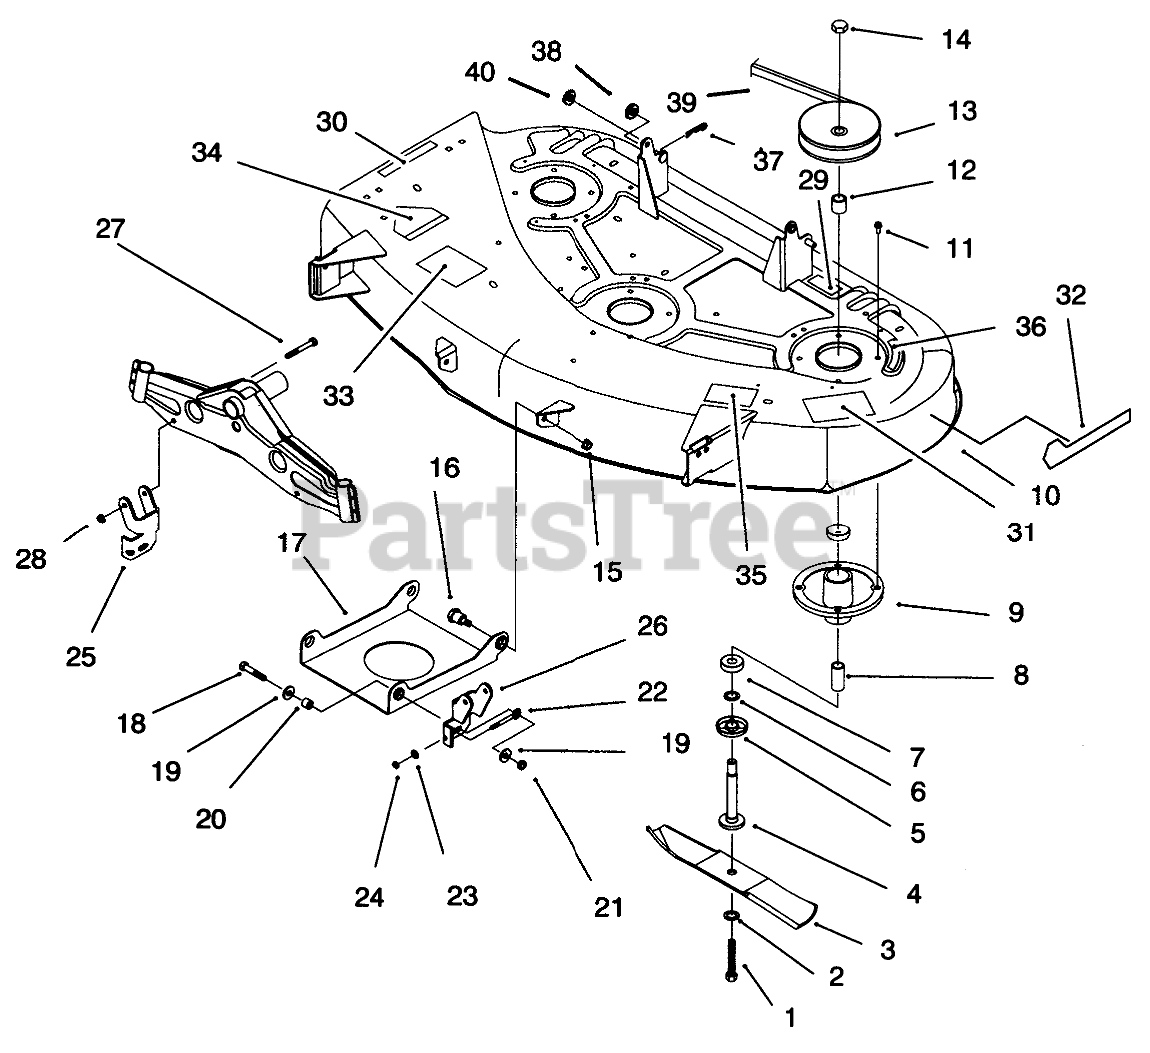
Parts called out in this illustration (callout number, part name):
1	SCREW-HH
2	WASHER-BELLEVILLE
3	Blade-Recycler
4	SHAFT-SPINDLE
5	SHIELD-BEARING
6	SPACER
7	BEARING-BALL
8	SPACER
9	HOUSING-SPINDLE
10	Deck Assembly
11	SCREW-TAPTITE
12	SPACER
13	PULLEY
14	NUT-HEX
15	NUT-LOCK, NI
17	Pan-Front Deck Susp.
18	SCREW-HH
19	WASHER-HARDENED
20	SPACER
21	NUT-LOCK, NI
22	SCREW-ADJUSTING
23	WASHER-FLAT
24	NUT-LOCK, NI
25	Bracket-Deck R.H.
26	Bracket-Deck L.H.
27	SCREW-HH
28	NUT-LOCK, NI
29	DECAL-WARNING
30	DECAL-DANGER, DEFLECTOR
31	DECAL-DANGER, THROWN OBJECT
32	DECAL - RECYCLER DECK
33	DECAL-INSTALL, BELT
34	DECAL-DANGER
35	DECAL-ADJUSTMENT, WHEEL
36	DECAL-DANGER, SHIELD
37	PIN-COTTER
38	WASHER-HARDENED
39	V BELT-DECK
40	WASHER-FLAT
